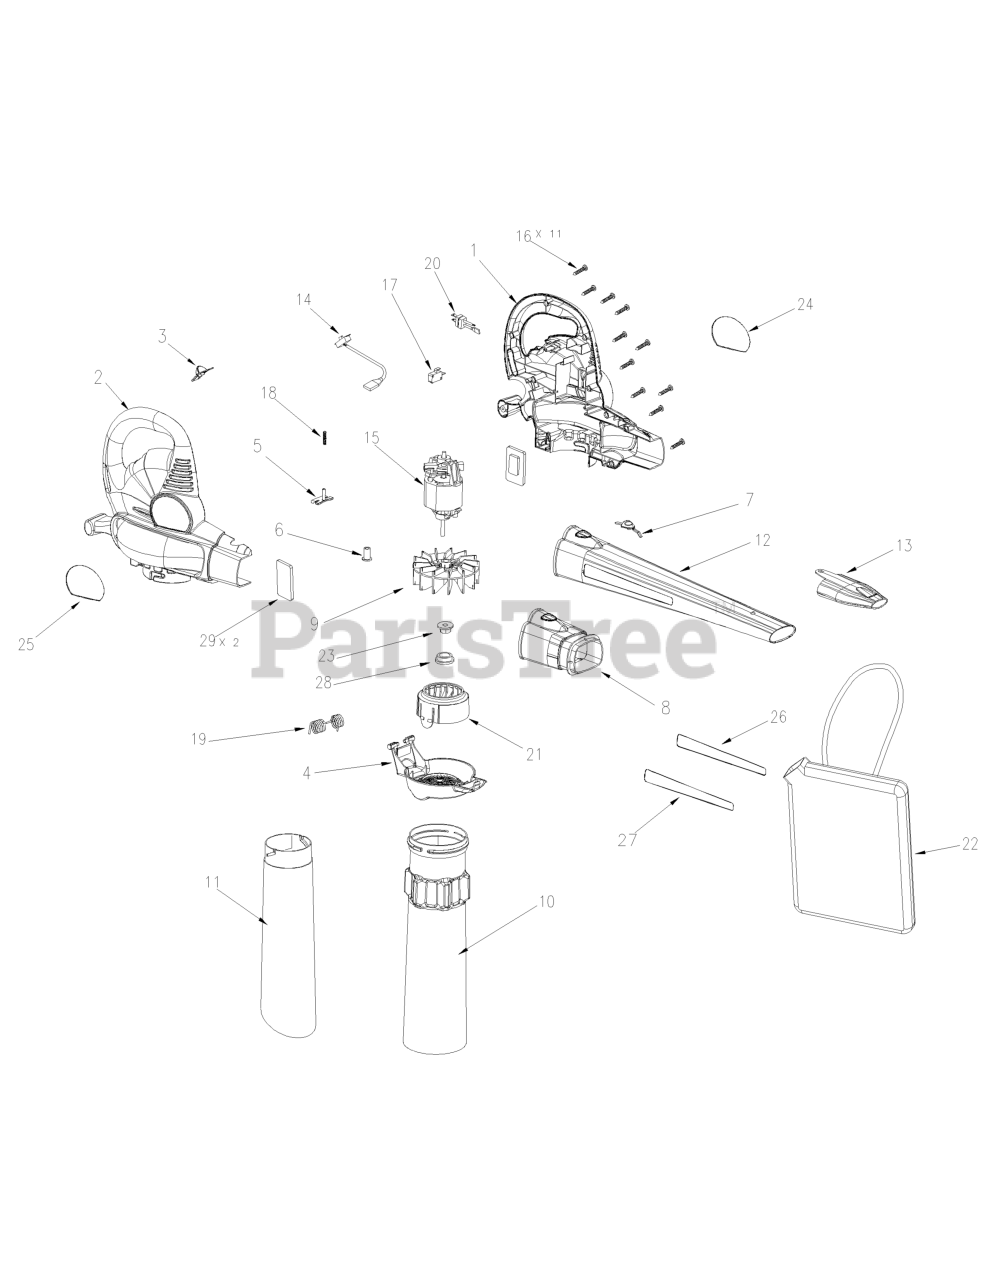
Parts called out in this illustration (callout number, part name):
1	HOUSING (R)
2	HOUSING (L)
4	VACUUM DOOR
8	CONNECTING PIPE
10	UPPER VACUUM TUBE
11	LOWER VACUUM TUBE
12	CONCENTRATOR NOZZLE
13	REGULAR NOZZLE
14	SWITCH ASS'Y
15	MOTOR ASS'Y
20	TERMINAL BLOCK
21	AIR COLLECTOR
22	VACUUM BAG
24	LABEL (R)
25	LABEL (L)
